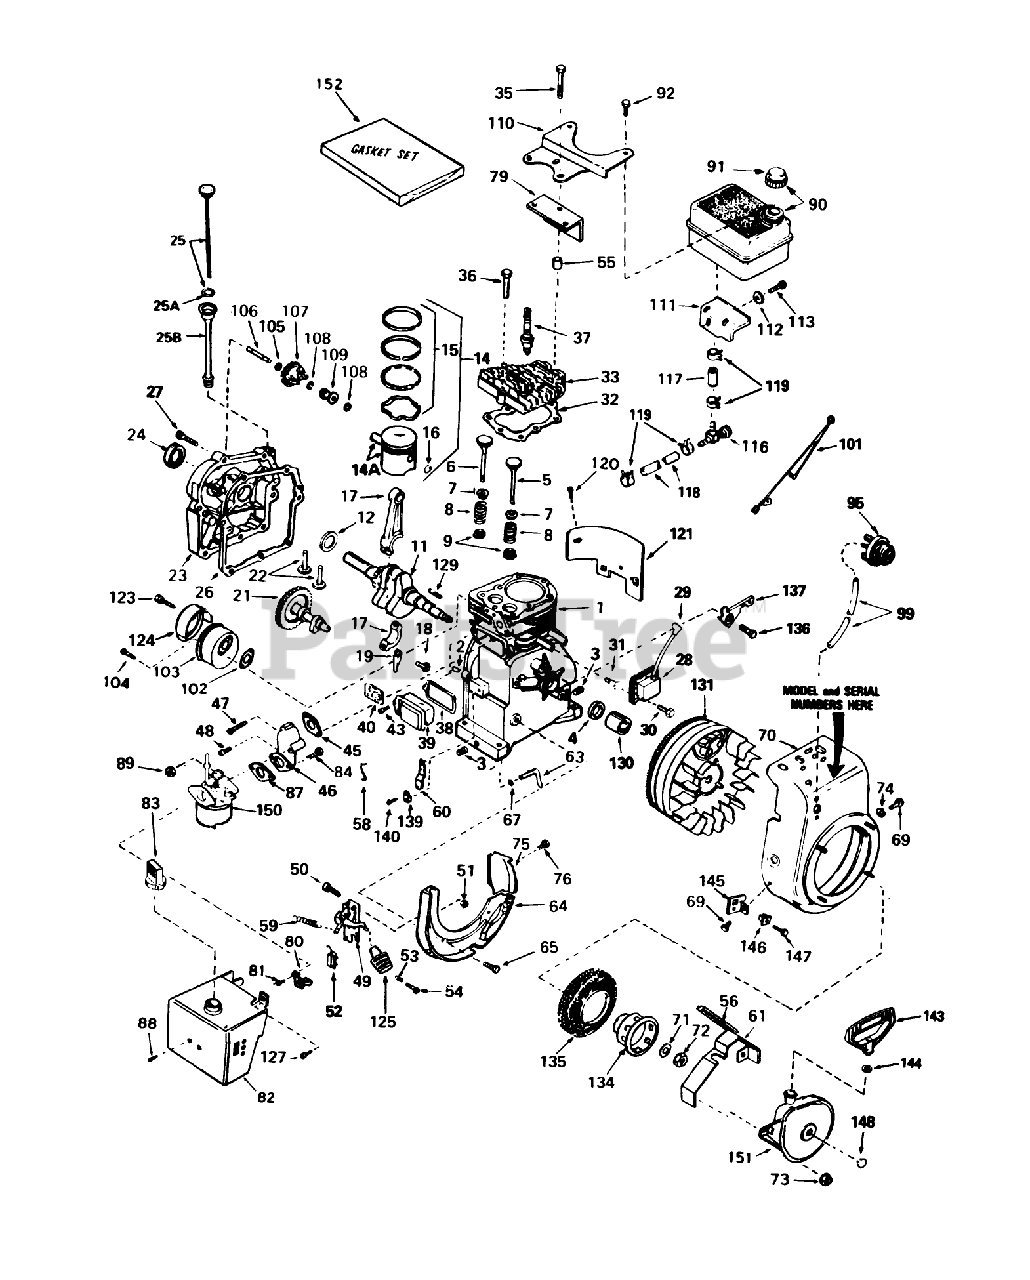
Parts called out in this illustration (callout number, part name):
1	Cylinder Assembly (Incl. Ref. #2, 3 35)
2	Pin-Dowel
3	Plug-Drain, Oil (SQH 1/4-18)
4	Seal-Oil
5	Valve, Intake (Std.) (Incl. Ref. #40)
5	Valve, Intake (1/32" oversize)(Incl. No. 40)
6	Valve, Exhaust (Std.)(Incl. No. 40)
6	Valve, Intake (1/32" oversize)(Incl. No. 40)
7	Cap-Upper Valve Spring
8	Spring-Valve
9	Cap-Valve, Spring
11	Crankshaft
12	Washer-Thrust
14	Piston-Pin Ring Assy. (Std.)(Incl. Ref. #14A, 15 16)
14	Piston-Pin Ring Assy. (.010 oversize)(Incl. Ref. #14A, 15 16)
14	Piston-Pin Ring Assy. (.020 oversize)(Incl. Ref. #14A, 15 16)
14A	Piston Pin Assy. (Std)(Incl. Ref. #16)
14A	Piston Pin Assy. (.010 oversize) (Incl. Ref. #16)
14A	Piston Pin Assy. (.020 oversize) (Incl. Ref. #16)
15	Piston Ring Set Std.
15	Piston Ring Set .010 O.S.
15	Piston Ring Set .020 O.S.
16	Ring-Retaining, Piston Pin
17	Rod Assembly, Connecting (Incl. Nos. 17 18)
18	Bolt-Rod, Connecting
19	Dipper-Oil
21	Camshaft (Compression Release)
22	Lifter-Valve
23	Cover, Cylinder (Incl. Ref. #24 106)
24	Seal-Oil
25	Dipstick
25A	O-Ring
25B	Tube Fill
26	Gasket-Cylinder Cover
27	Screw (1/4-20 x 1-1/4)
28	Solid State
29	Cover-Spark Plug
30	Screw
32	Gasket-Cylinder Head
33	CYLINDER HEAD
35	Screw (5/16-18 X 2)
36	Screw (5/16-18x1-1/2)
37	Plug, Spark (J17LM or equiv.)
37	Spark Plug-Resistor (R J19 L M)
38	Gasket Breather
39	Breather Assembly (Incl. Nos. 52 84)
40	Element-Breather
43	Screw
45	Gasket-Intake
46	Pipe-Intake (Incl. Ref. #47)
47	Screw-Hex Hd.
48	Screw (1/4-20 x 1-19/32)
49	Control Assembly, Speed (Incl. Ref. #155 thru 158 160)
50	Screw
51	Nut-Lock
52	Terminal
53	Spring-Compression
54	Screw
55	pacer
56	Seal, Snowguard
58	Jet-Main
59	Spring-Extension
60	Lever-Governor
61	Guard-Starter
63	Rod-Governor
64	Baffle-Blower Housing
65	Screw (1/4-20x19/32)
67	Washer-Flat
69	Screw
70	Housing-Blower
71	Washer-Belleville
72	Nut-Flywheel
73	Nut and Lock Washer (1/4-28)
74	Washer
75	Baffle-Extension
76	Screw-Hex Washer Hd.
79	Baffle-Heat
80	Bracket-Choke
81	Screw (10-32 x 1/2)
82	Cover-Carburetor
83	Knob-Choke
87	Gasket
88	Screw (8-32 X 5/16)
89	Nut and Lock Washer (1/4-28)
90	481-1261 SENATOR TI
91	Cap, Fuel
92	Screw (1/4-15x7/8)
95	Primer Assy.
99	Line-Primer
101	Ground Wire
102	Gasket Exhaust
103	Muffler
104	Screw
105	Washer-Flat
106	Shaft-Governor
107	Governor Gear ASM
108	Ring-Retaining
109	Spool-Governor
110	Plate-Fuel Tank
111	Bracket-Fuel Tank
112	Washer
113	Screw Assembly
116	Valve-Shut Off
117	Line-Fuel (8.62)
118	Line-Fuel
119	Clamp-Line, Fuel
120	Screw
121	Extension-Blower
123	Screw (1/4-15x7/8)
124	Cover-Muffler
125	Knob-Control
127	Screw (10-32x1/2)
129	Key-Flywheel
130	Spacer
131	CLAMP
134	Cup-Starter
135	Screen-Starter
136	Screw (10-24 x 9/16)
137	Bracket-Hold Down
139	Clamp-Lever, Governor
140	Screw
143	Handle-Starter, Mitten Grip
144	Washer
145	Bracket
146	Grommet
147	Screw
148	Plug-Starter
150	Carburetor (Incl. Ref. #87)
151	Starter-Rewind
152	Gasket Set (Incl. items marked*
